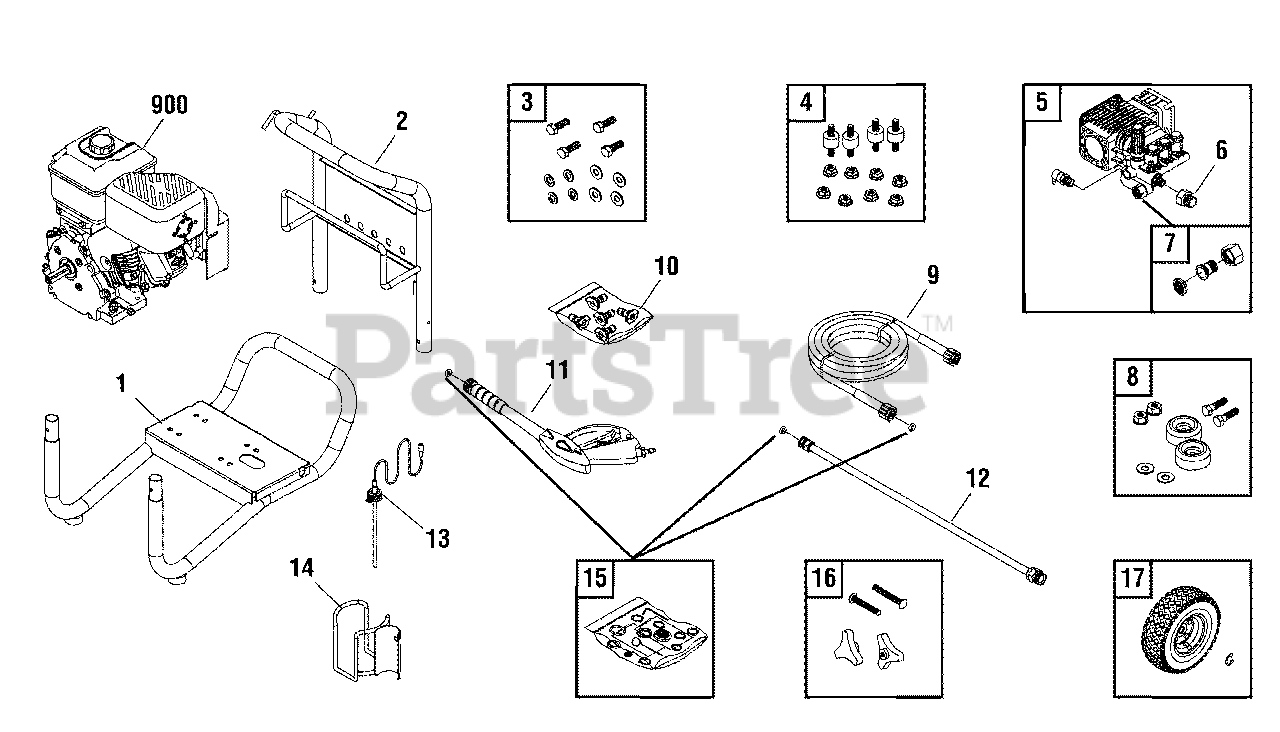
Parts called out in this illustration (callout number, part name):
3	KIT, Hardware, Pump Mounting
4	KIT, Vibration Mount
7	ADAPTER, Garden Hose
8	MOUNT, Vibration
10	KIT, QC Nozzles
11	GUN
12	EXTENSION, QC
15	O-RINGS
16	KIT, Hardware, Handle
